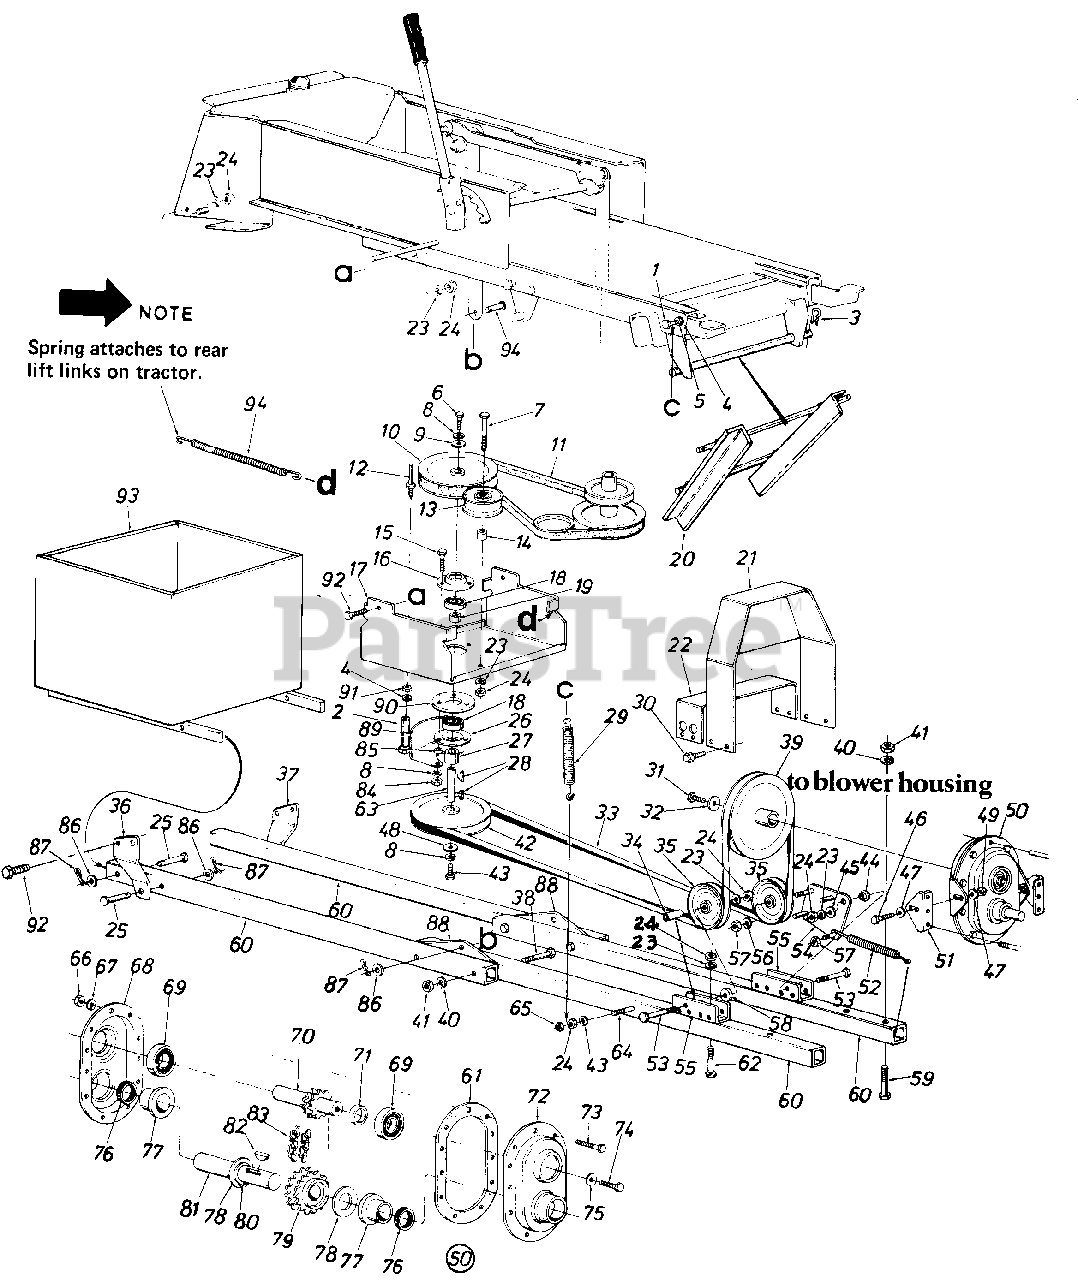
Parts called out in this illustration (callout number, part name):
1	Hex Bolt 1/4-28 x 1.50"
2	Clevis Pin Special 3/8" Dia. x 2.62" Lg.
3	Inter. Cotter Pin 1/2" Dia.
4	L.-Wash. 1/4" I.D.
5	Hex Nut 1/4-28 Thd.
6	Hex Boli 3/8-24 x 1.0" Lg.
7	Hex Bolt 3/8-16x 2.25" Lg.*
8	L.-Wash. 3/8" I.D.*
9	L.-Wash. .39" I.D. x 1.25" O.D.
10	5/8" "V" -Pulley .790" I.D. x 6.50 O.D
11	"V" Bell 1/2" x 52.0" Lg.
12	Belt Guard Pin 1/4" Dia. x 1.68" Lg.
13	Fl.-Idler w/flanges3.75" O.D.
14	Spacer .385" I.D. x .630" O.D. x.760" Lg.
15	Hex Bolt 5/16-24 x 1.50" Lg.
16	Open Brg. Housing 1.85" I.D.
19	Spacer 1.0" O.D. x .790" I.D. x.350" Lg.
20	Guide Bracket Ass'y.
21	Belt Cover Ass'y.
22	Belt Cover Brkt.
23	L.-Wash. 3/8" I.D.*
24	Hex Nut 3/8-16 Thd.*
25	Clevis Pin .50" Dia. x 2.75" Lg.
26	Bearing Housing 1.85" I.D.
27	Spacer .80" I.D. x 1.00" O.D. x.125" Lg.
28	Hi-Pro-Key 3/16 x 5/8"
29	Extension Spring 1.00" O.D. x 6.44" Lg.
30	Hex Wash. HD. Sf. Tap Scr. 5/16-24x.50" Lg.
31	Hex L.-Bolt 3/8-24 x 1.00" Lg.
32	Bell.-Wash. .400"I.D. x 1.25" O.D.
33	"V"-Belt 1/2" Ax 112.0" Lg.
34	Spacer.39" I.D. x .62" O.D. x 1.74" Lg.
35	5/8" "V"-Belt Idler 4.00" O.D.
39	5/8" "V"-Pulley 1.00" I.D. x 7.50" O.D.
40	L.-Wash. 1/2" I.D.*
41	Hex Nut 1/2-13 Thd.*
42	5/8" "V"-Pullev .79"I.D. x6.5"
43	Hex Bolt 3/8-24 x 1.0" Lg.
44	Shoulder Spacer .625" I.D.
45	Fl.-Wash. .400" I.D. x 1.25" O.D
46	Hex Bolt 5/16-18 x .75" Lg.*
47	Belh-Wash. .345" I.D. x .88"O.D.
48	Fl.-Wash. .39" I.D. x 1.25" O.D.
49	Hex Nut 5/16-18 Thd.*
50	Comp. Chain Gear Box Ass'y.
51	Gear Box Support Brkt.
52	Extension Spring .87" Dia. x 6.00" Lg.
53	Hex Bolt 3/8-16 x 3.0" Lg. (Grade 8)
56	Fl.-Wash. .385"1.D. x .87 O.D.
57	Hex I ns. L.-Nut 3/8-24 Thd.
58	Fl.-Wash. .400" I.D. x 1.25" O.D. x .157 Thk.
59	Hex Bolt 1/2-13 x 3.00" Lg.*
62	Hex Bolt 3/8-16 x 3.0" Lg. (Grade 8)
63	Shaft - .787" Dia. x 3.81" Lg.
64	Hex Bolt 3/8-16 x 3.25" Lg.*
65	Hex Cent. L.-Jam Nut 3/8-16 Thd.
66	Hex Nut 1/4-28 Thd.
67	Spr.-Wash. .270" I.D. x.57" O.D
68	Gear Hsg. Half - L.H.
69	Ball Brq. 1.00"I.D. x 2.00" O.D.
70	11-2x.5 Pitch-Sprkit.ShaftAss'y.
71	Spacer 1.00" I.D. x 1.18" O.D. x .440 Lg.
72	Gear Hsg. Half - R.H.
73	Hex Bolt 1/4-28 x 1.00" Lg. (Grade 5)
74	Hex L.-Bolt 3/8-24 x 1.00" Lg.
75	Bell.-Wash. .400" I.D. x 1.25" O.D.
76	Oil Seal 1.25" x 1.75" O.D.
77	Flange Brg. 1.252" I.D.
78	Fl.-Wash. 1.25" I.D. x 2.00" O.D.
79	DBL Sprkt. 19-2 Teeth x .500" Pitch
80	Snap Ring for 1.25" Dia. Shaft
81	Gear Shaft 1.25" Dia. x 6.0" Lg.
82	#A Hi-Pro Key 1/4 x 7/8" Dia.
83	40-2 Chain 1/2" Pitch x 25 Links
84	Hex Nut 5/16-24 Thd.*
85	Spacer .380" I.D. x .625" O.D. x.227" Lg.
86	Fl.-Wash. .510" I.D. x 1.0" O.D.
87	Inter. Cot.-Pin 1/2" Dia.
91	Hex Nut 1/4-20 Thd.
92	Hex Bolt 3/8-16 x 1.0" Lg.-Gr. 5
93	Weight Box Ass'y.
